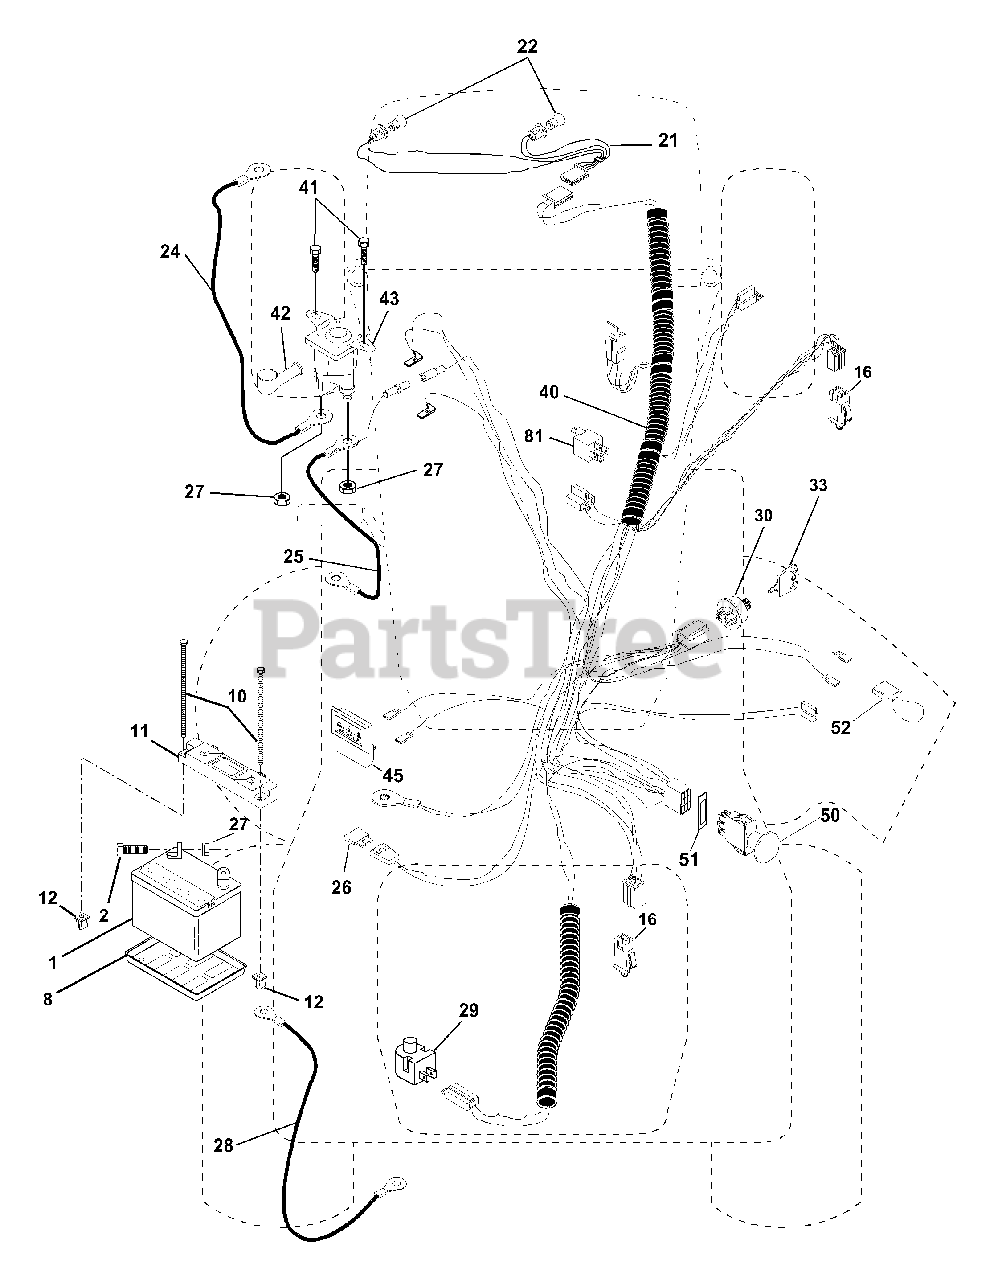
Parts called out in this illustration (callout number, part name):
1	Battery
2	Bolt Hex Head 1/4-20 x 3/4
8	Tray, Battery
10	Bolt, Battery Front 1/4-20 x 7.5 Zinc
11	Holddown Battery Front Mount
12	Nut, Push Nylon 1.4" Battery Front
16	Switch Interlock Push-In
21	Harness Socket Light w/4152J
22	Bulb Light
24	Cable, Battery
25	Cable, Battery
26	Fuse
27	Nut Keps Hex 1/4-20
28	Cable,Ground
29	Switch, Plunger Normal Op Olive
30	Switch, Ign
33	Key
40	Harness Ign.
41	Screw 1/4-20 x 1/2
42	Cover, Terminal Red
43	Solenoid
45	Ammeter
50	Switch, PTO
51	Ring Retainer PTO
52	Protection, Wire, Loop
81	Relay Asm.
